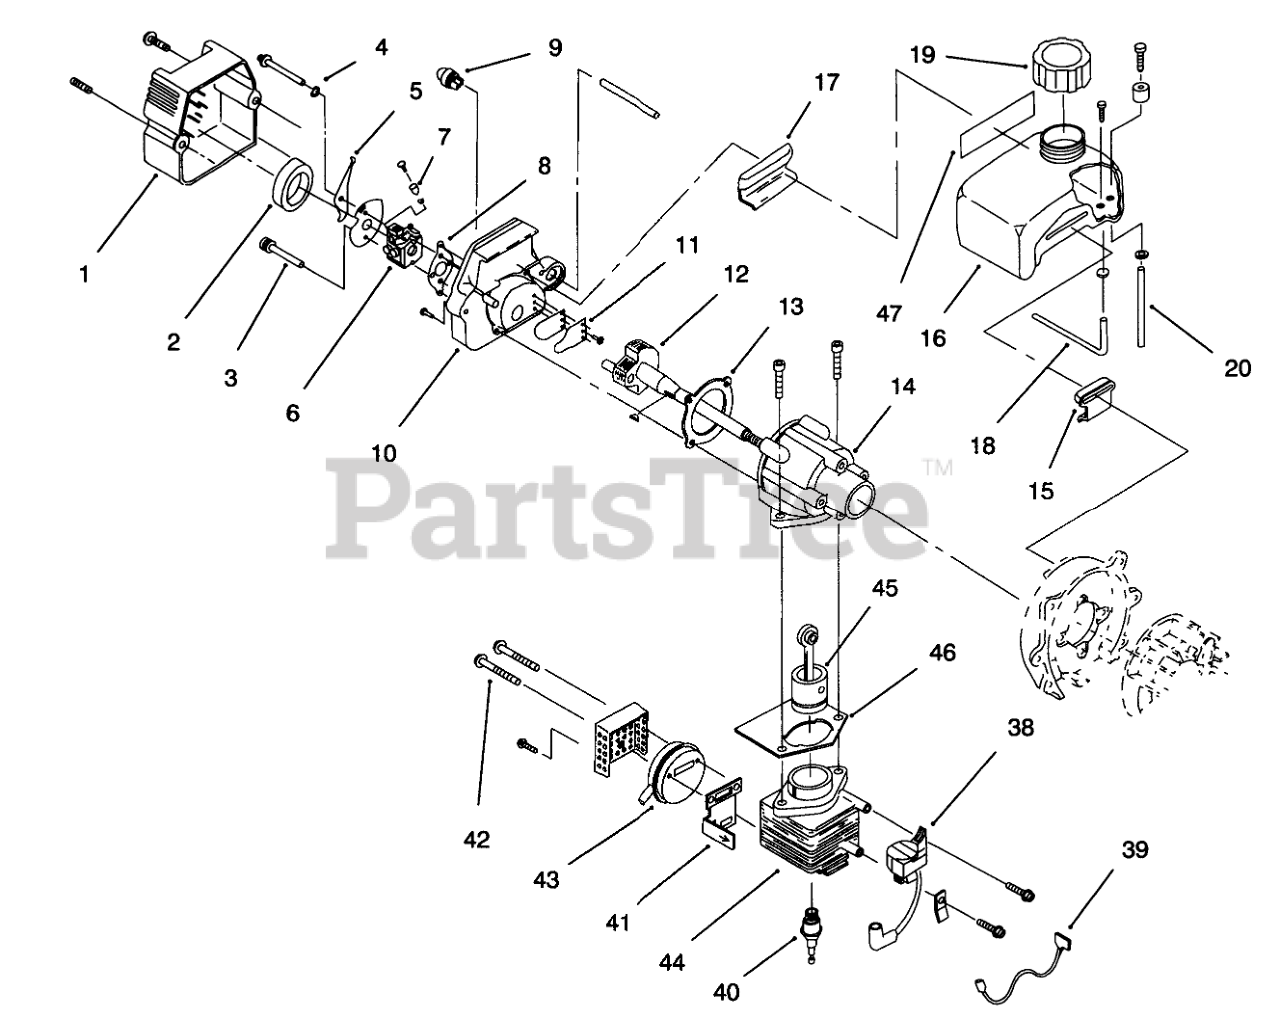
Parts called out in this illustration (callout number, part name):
1	Carburetor/Air Cleaner Asm. (Incl. Ref. #2)
2	FILTER - AIR CLEANER
3	ASSEMBLY - MOUNTING BOLT
4	WASHER - WAVEY
5	LEVER - CHOKE & PLATE
6	Carburetor
7	THROTTLE ADJ ASM
7	ASM - THROTTLE ADJUSTMENT
8	CARBURETOR GASKET(10 PER PACK)
9	PRIMER & HOSE ASM
10	Carburetor Mount Asm. (Incl. Ref. #11-13)
11	ASSEMBLY - REED
12	ASM - POWER SHAFT
13	CARB MT GASKET (10-PK)
14	Crankcase Service Asm. (Incl. Ref. #12)
15	FRONT MOUNTING PAD
16	Fuel Tank Asm. (Incl. Ref. #21-23)
17	REAR MOUNTING PAD
18	FUEL RETURN LINE ASM
19	FUEL TANK CAP
20	FUEL LINE ASM
38	Module Asm.
39	LEAD - WIRE
40	SPARK PLUG
41	GASKET - EXHAUST
42	ASM - MUFFLER MTG BOLT
43	Muffler Asm.
44	ASSEMBLY - CYLINDER
45	PISTON & ROD ASM
46	CYLINDER GASKET
47	Decal-Fuel & Oil Mix
